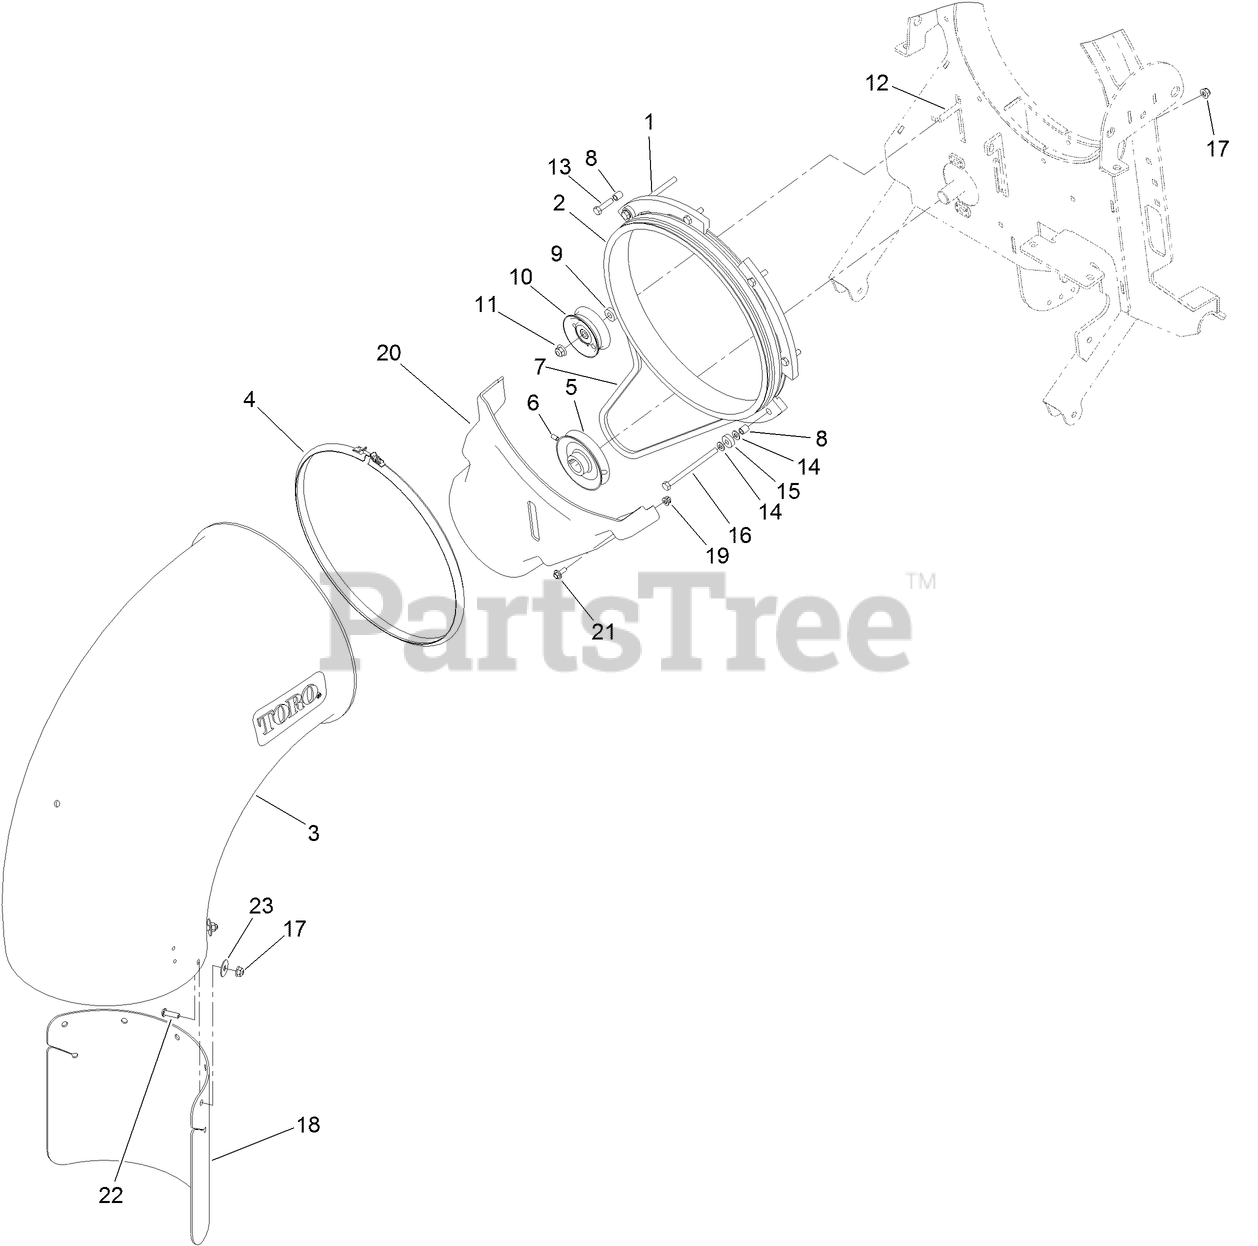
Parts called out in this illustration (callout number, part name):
1	GUIDE-NOZZLE
2	PULLEY-NOZZLE
3	NOZZLE
4	CLAMP-NOZZLE
5	PULLEY
6	SCREW-SET, HSH
7	BELT-V
8	SPACER
9	SPACER
10	PULLEY-IDLER, FLAT
11	NUT-HF, NI
12	BOLT-CARRIAGE
13	SCREW-HH
14	WASHER-FLAT
15	BEARING-BALL
16	SCREW-HH
17	NUT-HF, NI
18	EXTENSION-NOZZLE
19	NUT-CLIP
20	COVER-BELT
21	SCREW-HWH
22	SCREW-HSBH
23	WASHER-FLAT
